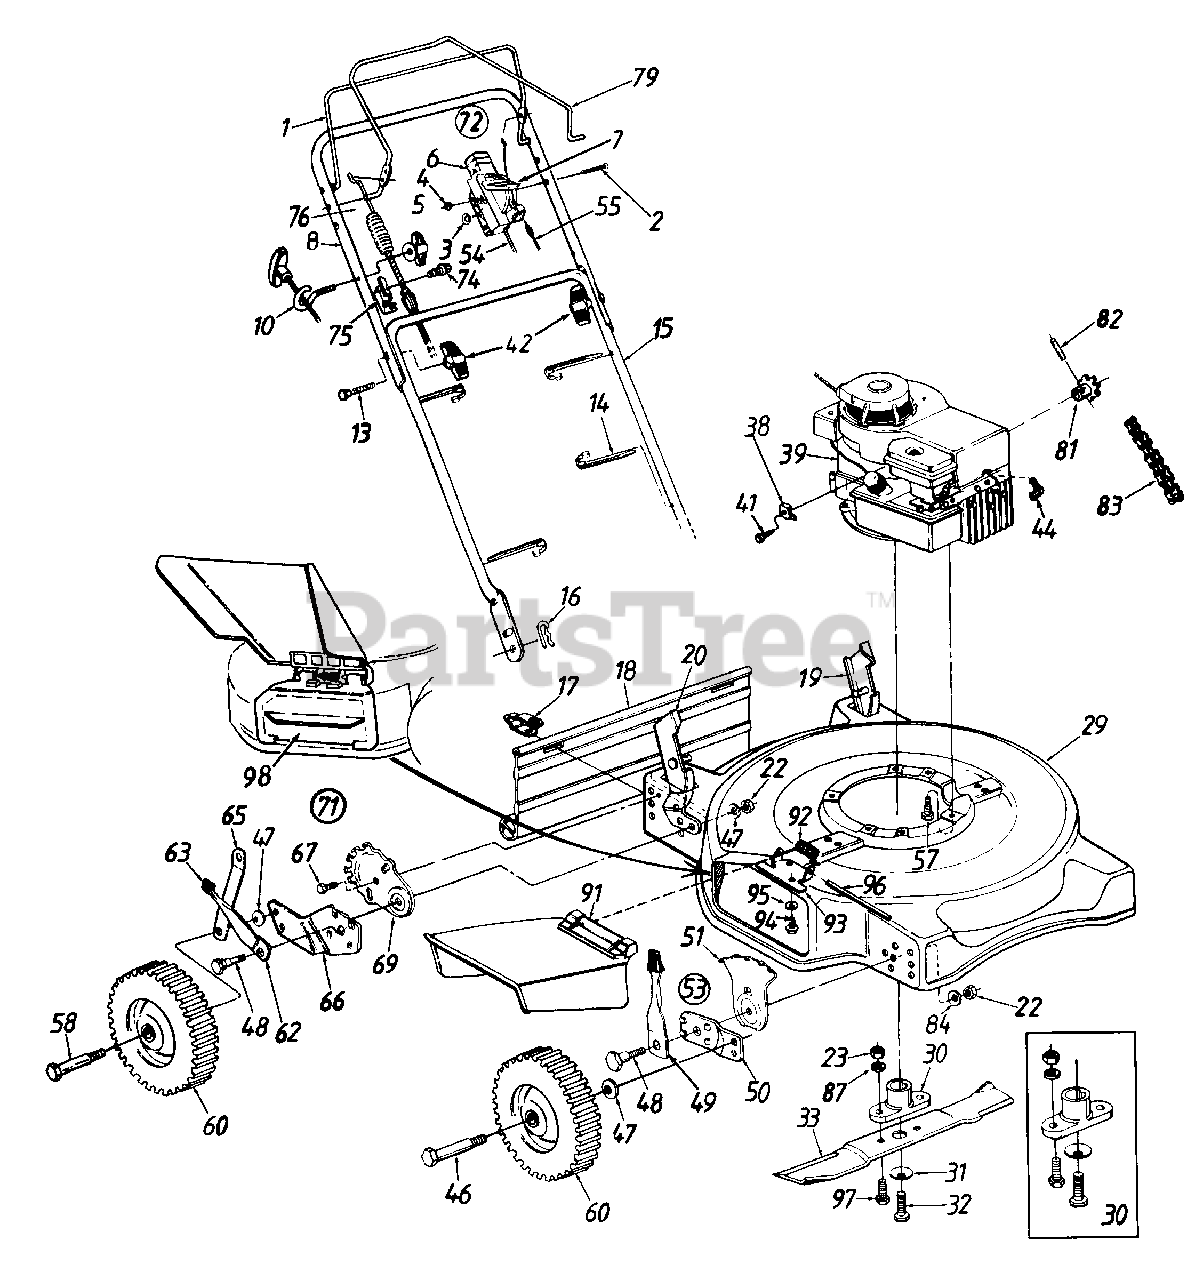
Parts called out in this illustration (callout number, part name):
2	Oval C-Sunk Mach. Scr.
3	Spr. Wash .66" I.D.
4	Hex L-Nut 1/4-20 Thd.
5	Handle Knob 1/4-20 Thd.
6	Throttle Body
7	Throttle Lever
13	Curved Hd. Bolt 5/16-18 x 2" Lg.
14	Cable Tie
16	Hairpin Cotter
17	Hinge Clip
18	Rear Flap
23	Hex Nut 3/8-24 Thd.
29	22" Deck Ass'y.
30	Blade Adapter Kit
31	Bell-Wash .39" I.D.
32	Hex Bolt 3/8-24 x 1.5" Lg.
33	22" Blade
38	Cable Clamp (B&S)
39	Engine
41	Hex Wash. Hd. Scr. #10-32 x .62" Lg. (B&S)
42	Hand Knob
44	Spark Plug Boot
46	Front Axle Bolt
47	Bell-Wash .400" I.D. x .88"
48	Shld. Bolt .50" Dia. x .357"
49	Spring Lever Ass'y. w/Knob
51	Height Adj. Plate
53	Height Adj. Ass'y. Comp.- R.H.
54	Throttle Control Wire - 51" Lg. (B&S)
55	Control Cable - 39" (B&S)
57	Hex L-Wash. Hd. Scr. 3/8-16 x 1.0" Lg.
58	Rear Axle Bolt
60	Wheel Ass'y. Comp.
62	Spring Lever
63	Spring Lever Knob
67	Hex AB-Tap 1/4-.62" Lg.
69	Index Plate
71	Rear Height Adj. Ass'y.- R.H.
72	Throttle Box Comp.
74	Hex Wash. AB-Tap Scr. 5/16 x .75" Lg.
75	Cable Brkt.
76	Clutch Cable
82	Spring Pin Spir. 3/16" Dia. x 1" Lg.
83	#48 Chain 1/2" Pitch 50 Links (Endless)
84	Bell-Wash .39" I.D. x 1.38"
87	L-Wash. 3/8" I.D.
91	Chute Deflector Ass'y.
92	Torsion Spring
93	Adapter Plate
94	Hex Self-Tap Scr. 1/4-20 x .5" Lg.
95	Bell-Wash. 1/4" I.D.
96	Hinge Pin
97	Hex Bolt 3/8-24 x 1" Lg.
98	Mulching Plug
